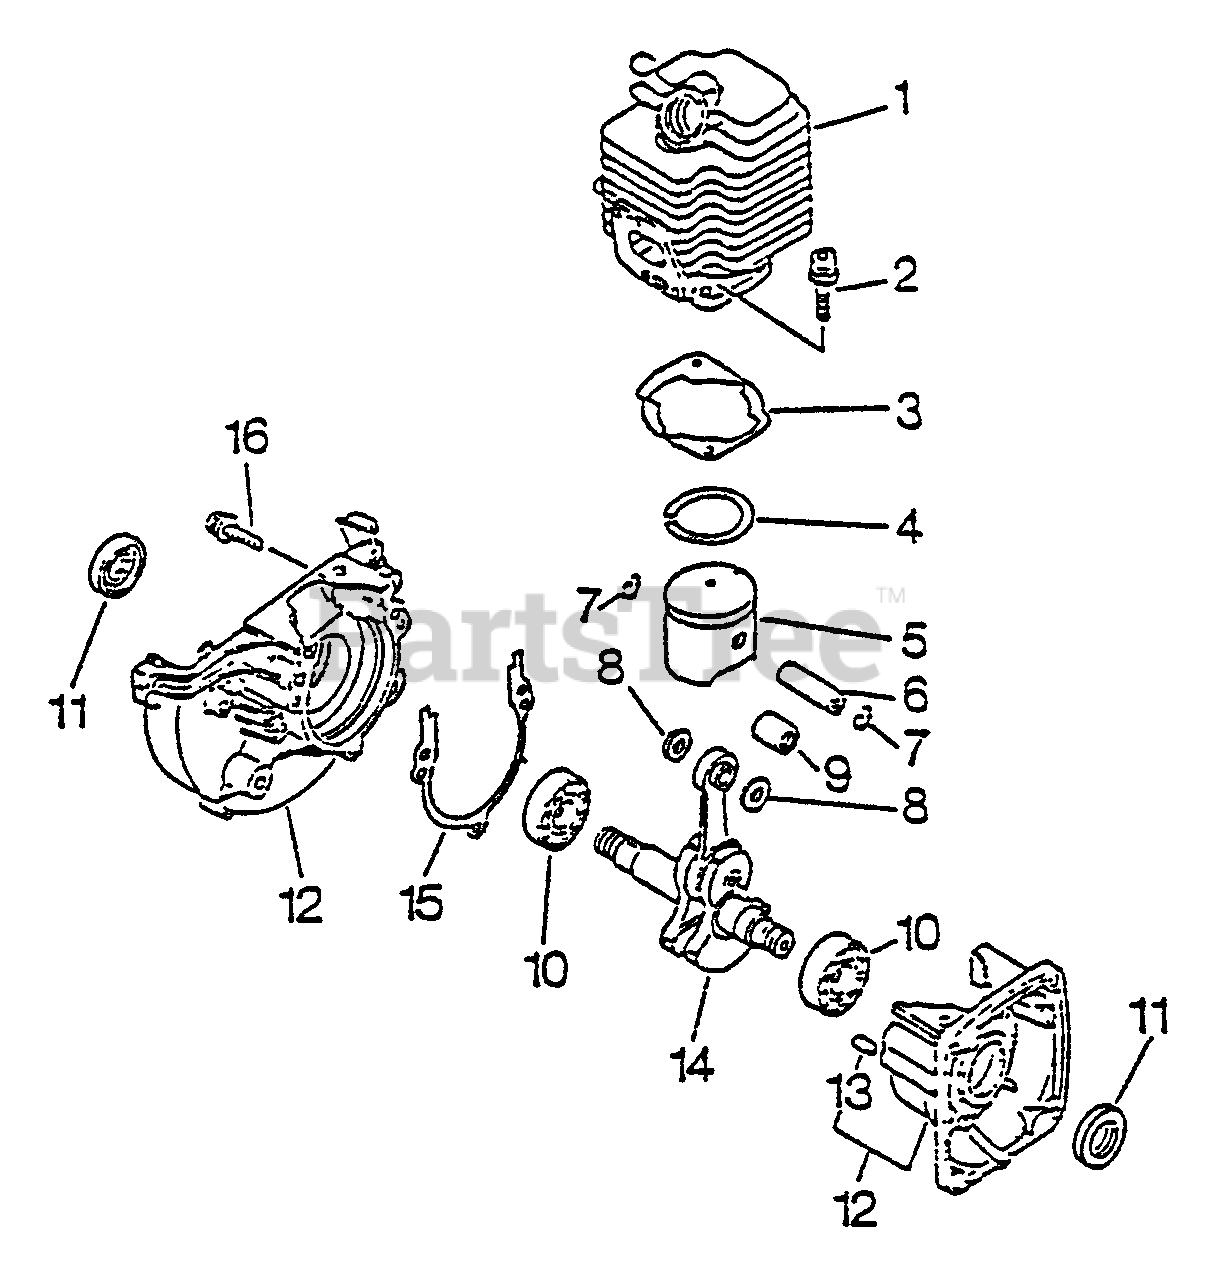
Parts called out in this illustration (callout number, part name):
2	BOLT 5×22
3	GASKET, CYLINDER
4	RING, PISTON
5	PISTON
6	PIN, PISTON 8
7	RING, SNAP
8	WASHER, THRUST
9	BEARING, NEEDLE
10	BEARING, BALL - 6201 C3
11	SEAL, OIL 12
12	CRANKCASE KIT
13	PIN, LOCATING 4
14	CRANKSHAFT ASSY
15	GASKET, CRANKCASE
16	BOLT 5×28
